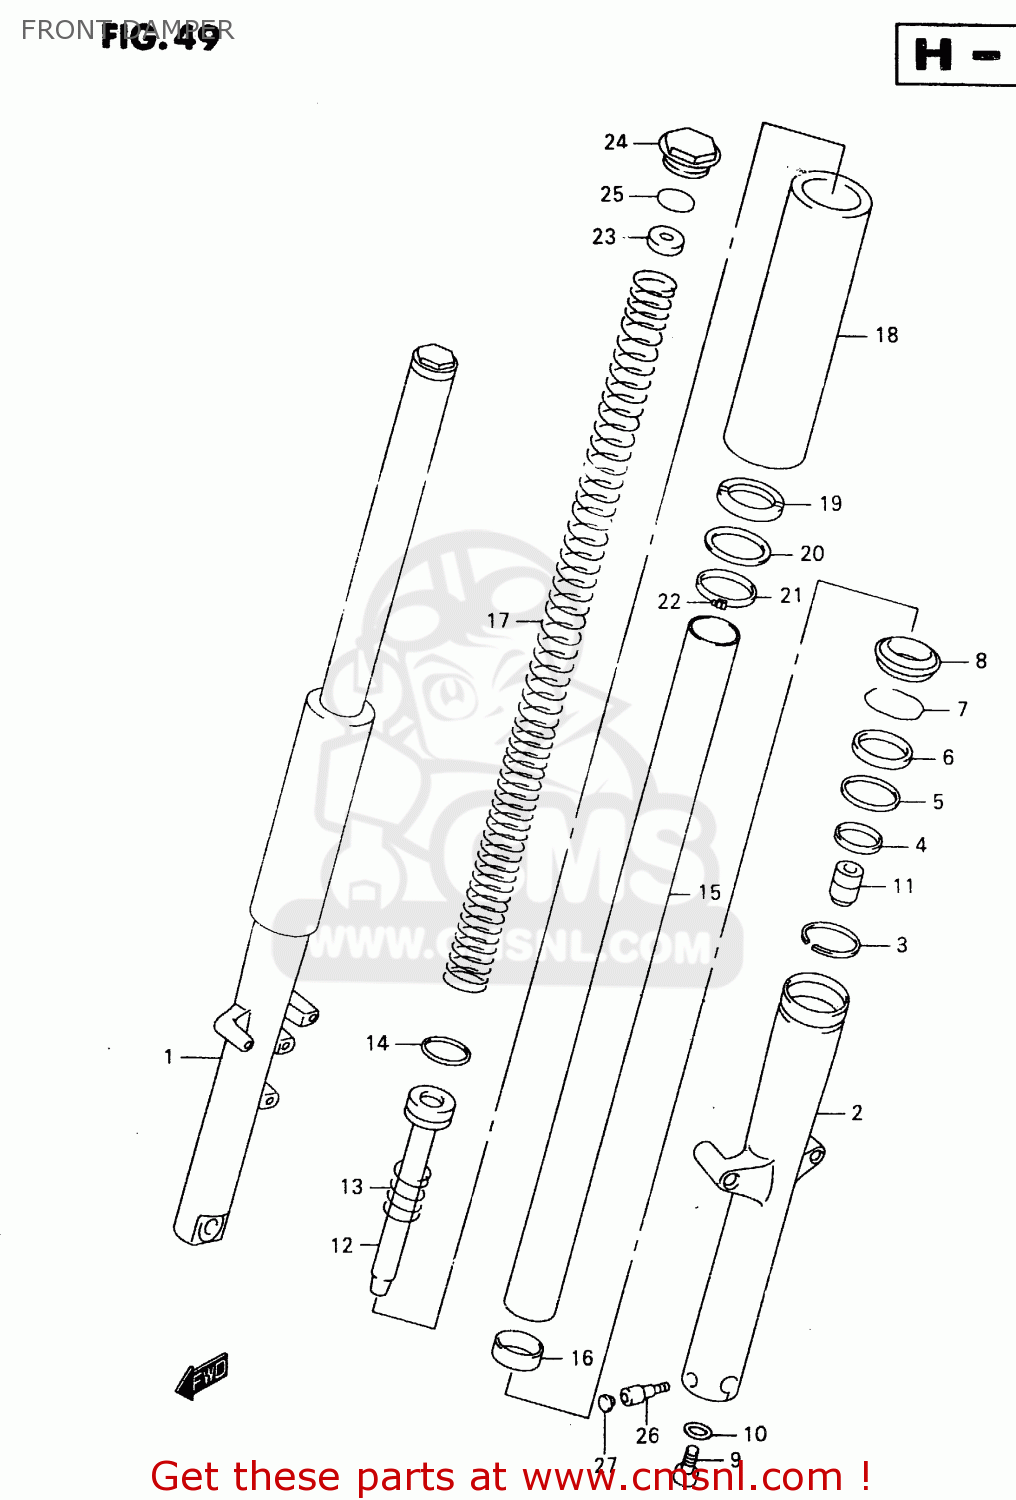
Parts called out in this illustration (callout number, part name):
1	TUBE,OUTER,R
2	TUBE,OUTER,L
3	GUIDE,CASE
4	BUSH,GUIDE
5	SPACER,SEAL
6	SEAL,OIL
7	CIRCLIP,FORK OIL SEAL
8	SEAL,DUST
9	BOLT,CENTER (8X18)
10	GASKET (NAS)
11	PIECE,OIL LOCK
12	SEAT,PIPE
13	SPRING,REBOUND
14	RING,PISTON
15	TUBE,INNER
16	BUSHING,SLIDE
17	SPRING,FR
18	CASE,UNDER
19	SEAT,RUBBER
20	WASHER
21	SPACER
22	BOLT
23	BOLT,FORK INNER
24	BOLT
25	O RING
26	BOLT
27	CAP(OD:14.5)
